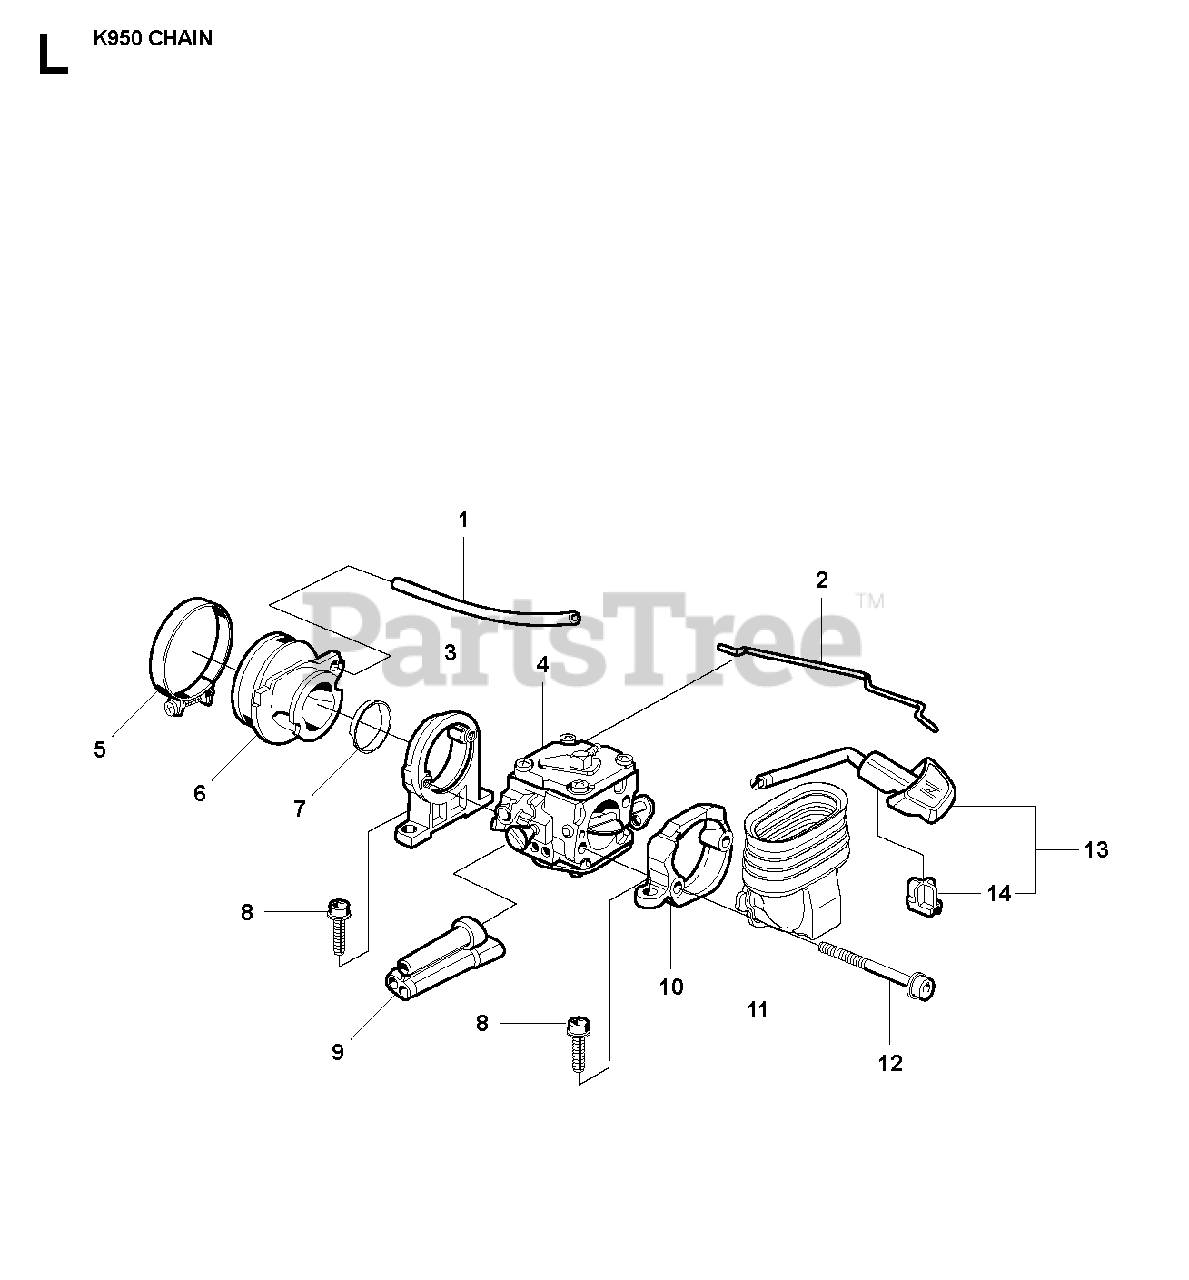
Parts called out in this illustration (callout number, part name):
1	IMPULSE HOSE
3	CARBURETTOR BRACKET
4	CARBURETTORHS 282-A
8	SCREW IHSCFM
12	SCREW IHSCFM
13	CHOKEIncl. 14
14	WEAR PROTECTION
